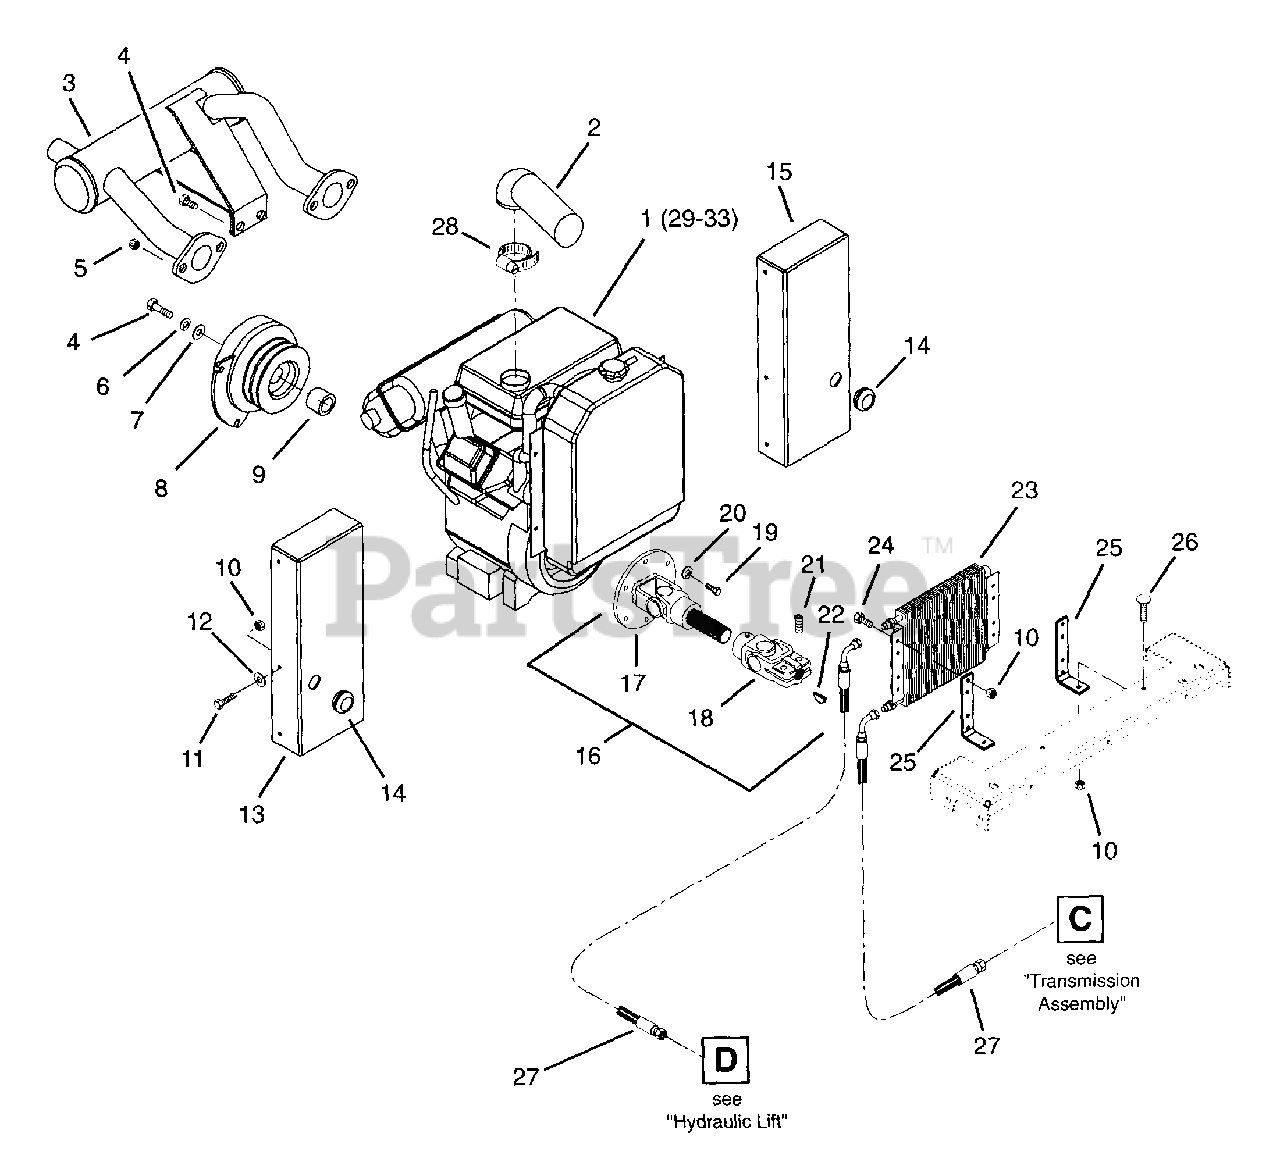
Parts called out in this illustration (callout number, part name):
1	Engine, Kawasaki 22 HP
2	Hose, Air Intake
4	Bolt-Hex M10 x 1.5 x 20 Grade 5
5	Nut-Hex M6 x 1.0
6	Washer-Locking .44 x .109 Regular
7	Washer-Flat-Steel .44 x 1.625 x .315
8	Clutch, Electric
10	Nut-Locking-Center .25-30
11	Bolt-Hex .25-20 x .75 Grade 5
12	Washer-Flat-Steel .281 x .62 x .065
13	Deflector, Air Right Hand
14	Grommet, 1.25 x 1.50 x 1.81
15	Deflector, Air Left Hand
16	Driveline, Universal
17	Adapter, Flywheel
18	Assembly, U-Joint
19	Bolt-Hex 8mm x 1.25 50mm
20	Washer-Locking .31 x .078 Regular
21	Screw-Set .38-16 x .50
22	Key-Woodruff .188 x .75 x .313 SAE9
23	Cooler, Oil
24	Bolt-Hex .25-20 x .50 Grade 5
25	Bracket, Oil Cooler Mount
26	Bolt-Round Head Square Neck .25-20 x .75 Grade 5
27	Assembly, Hydraulic Hose-Oil Cooler To Filter
28	Clamp, 2.25 Diameter Hose
29	Air Cleaner
30	Air Filter Element
31	Fuel Filter
32	Oil Filter
33	Spark Plug
